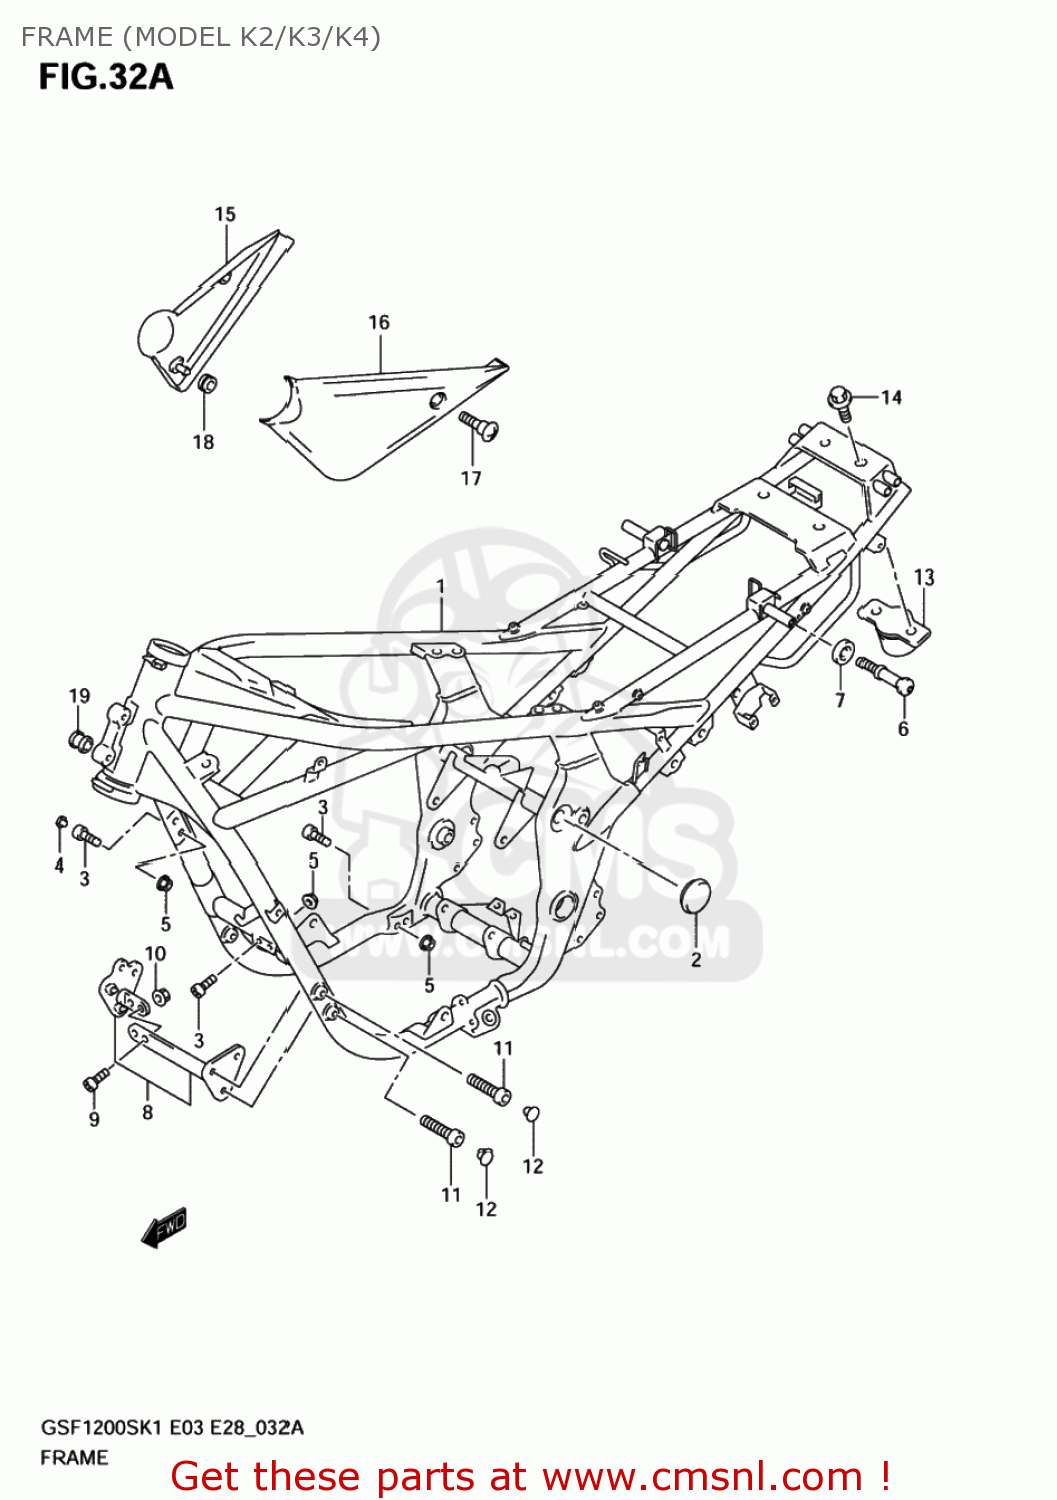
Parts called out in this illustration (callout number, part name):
1	FRAME (BLUE)
2	CAP,FRAME BODY
3	BOLT(10X37)
4	CAP(OD:12)
5	NUT
6	HOOK,SEAT RAIL
7	WASHER,HOOK
8	PLATE,ENGINE MOUNT NO.1
9	BOLT
10	NUT
11	BOLT
12	CAP(OD:12)
13	DAMPER,FRAME RR
14	BOLT
15	COVER,FRAME HEAD,R
16	COVER,FRAME HEAD,L
17	SCREW(5X12)
18	CUSHION
19	CUSHION,COWLING BRACE
